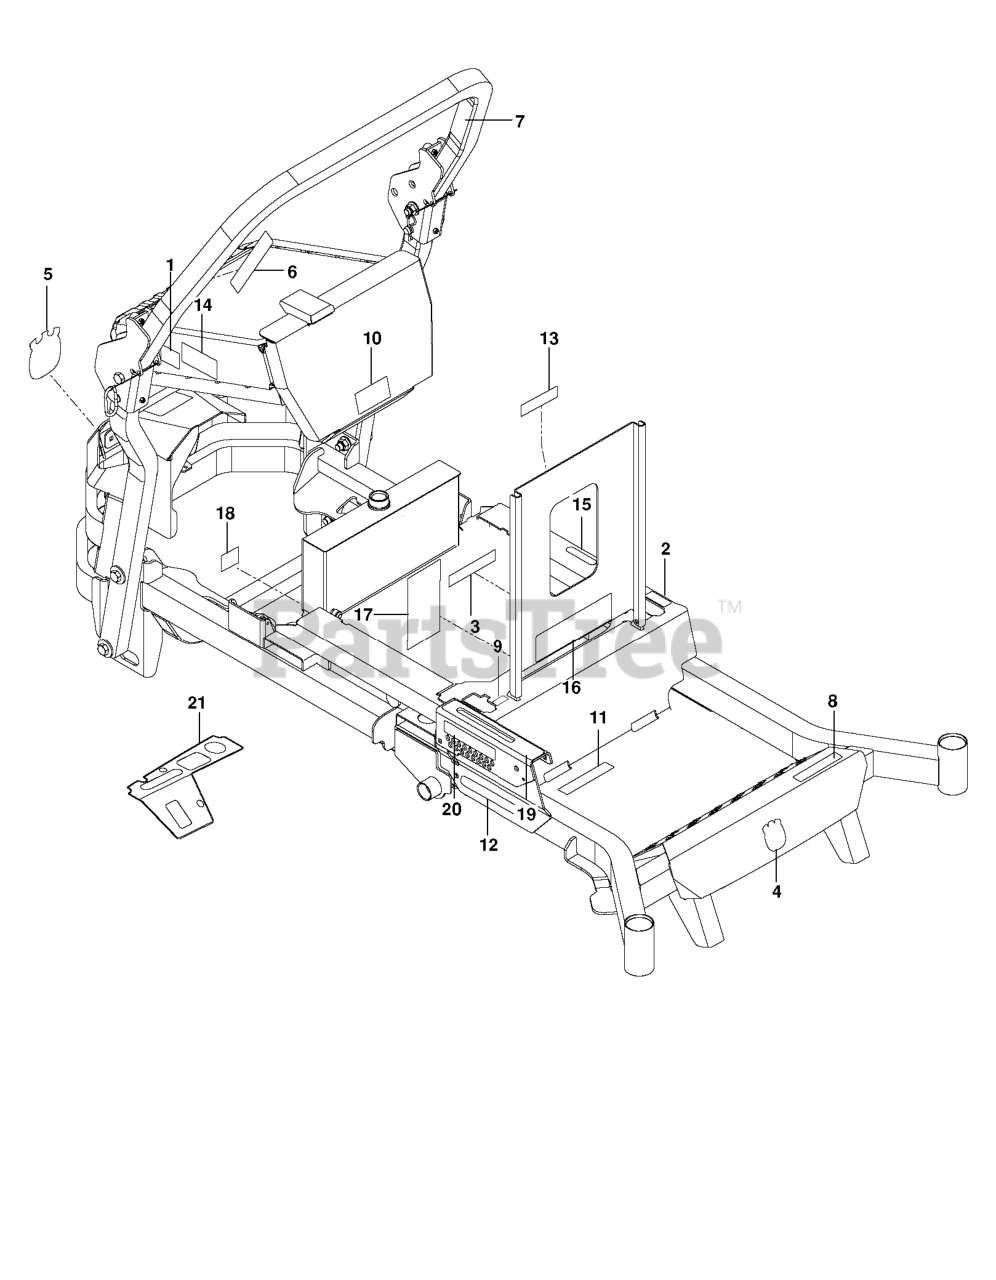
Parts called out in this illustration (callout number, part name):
1	DECAL, DEBRIS SCREEN
2	DECAL, MOTION CONTROL
3	EURO DECAL-BATTERY WARNIN6
4	DECAL.AUGER.HUSQ.CROWN.SNOW
5	DECAL, CROWN H, 110MM
6	DECAL, ROPS, WARNING
7	DECAL, ROPS, DIESEL
8	DECAL, PZ29D
9	DECAL, F.S.T.
10	DECAL, BELT DRIVE
12	RP.DECAL.BADGE.170MM.TEXTLOGO
13	DECAL, FUSE, DIESEL
14	DECAL, HOT
15	DECAL, PARK BRAKE
16	DECAL, WARNING
17	DECAL, SERVICE, DIESEL
18	DECAL, HYDRO BELT
19	DECAL, HEIGHT CE
20	DECAL, HEIGHT CE
21	DECAL, CONTROL, DIESEL
